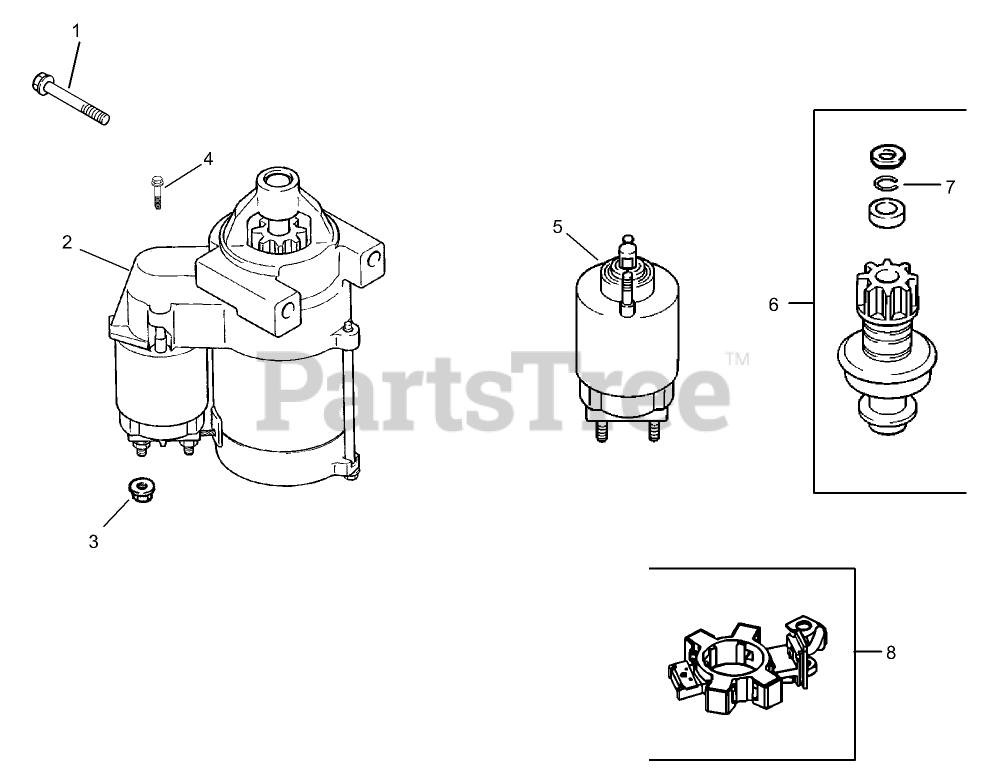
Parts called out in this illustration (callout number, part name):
1	SCREW-FLG (M8X1.25X80)
2	Starter, solenoid shift (Includes 3-8)
3	NUT-FLANGE (M8X1.25)
4	SCREW-TORX HEAD, EXTERNAL
5	Kit, solenoid (Includes 4)
6	Kit, drive (Includes 7)
7	RING-RETAINING
8	BRUSH HOLDER KIT
